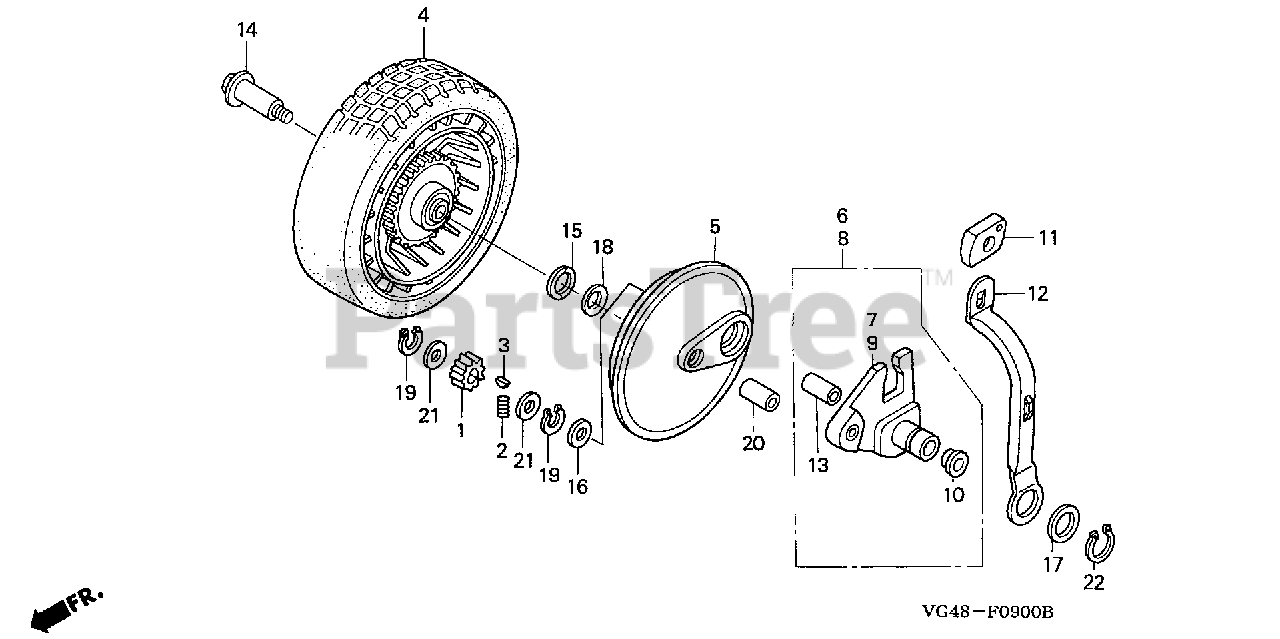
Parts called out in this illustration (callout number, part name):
1	GEAR, PINION (12T)
2	SPRING, RATCHET RETURN
3	KEY, RATCHET
4	WHEEL, RR.
6	ARM, R. RR. ADJUSTING
7	ARM, R. RR. ADJUSTER
8	ARM, L. RR. ADJUSTING
9	ARM, L. RR. ADJUSTER
10	DUST SEAL (12.7MM)
11	GRIP, ADJUSTER
12	PLATE, RR. ADJUSTER
13	BUSH, DRIVESHAFT
14	BOLT, RR. WHEEL SHAFT
15	WASHER, WHEEL
16	WASHER, THRUST (13MM)
17	WASHER, FLAT (26X44)
18	WASHER, THRUST (13X27X1)
19	CIRCLIP (OUTER) (12.7MM)
20	COLLAR, THRUST
21	COLLAR, PINION GEAR
22	CIRCLIP (OUTER) (25MM)
